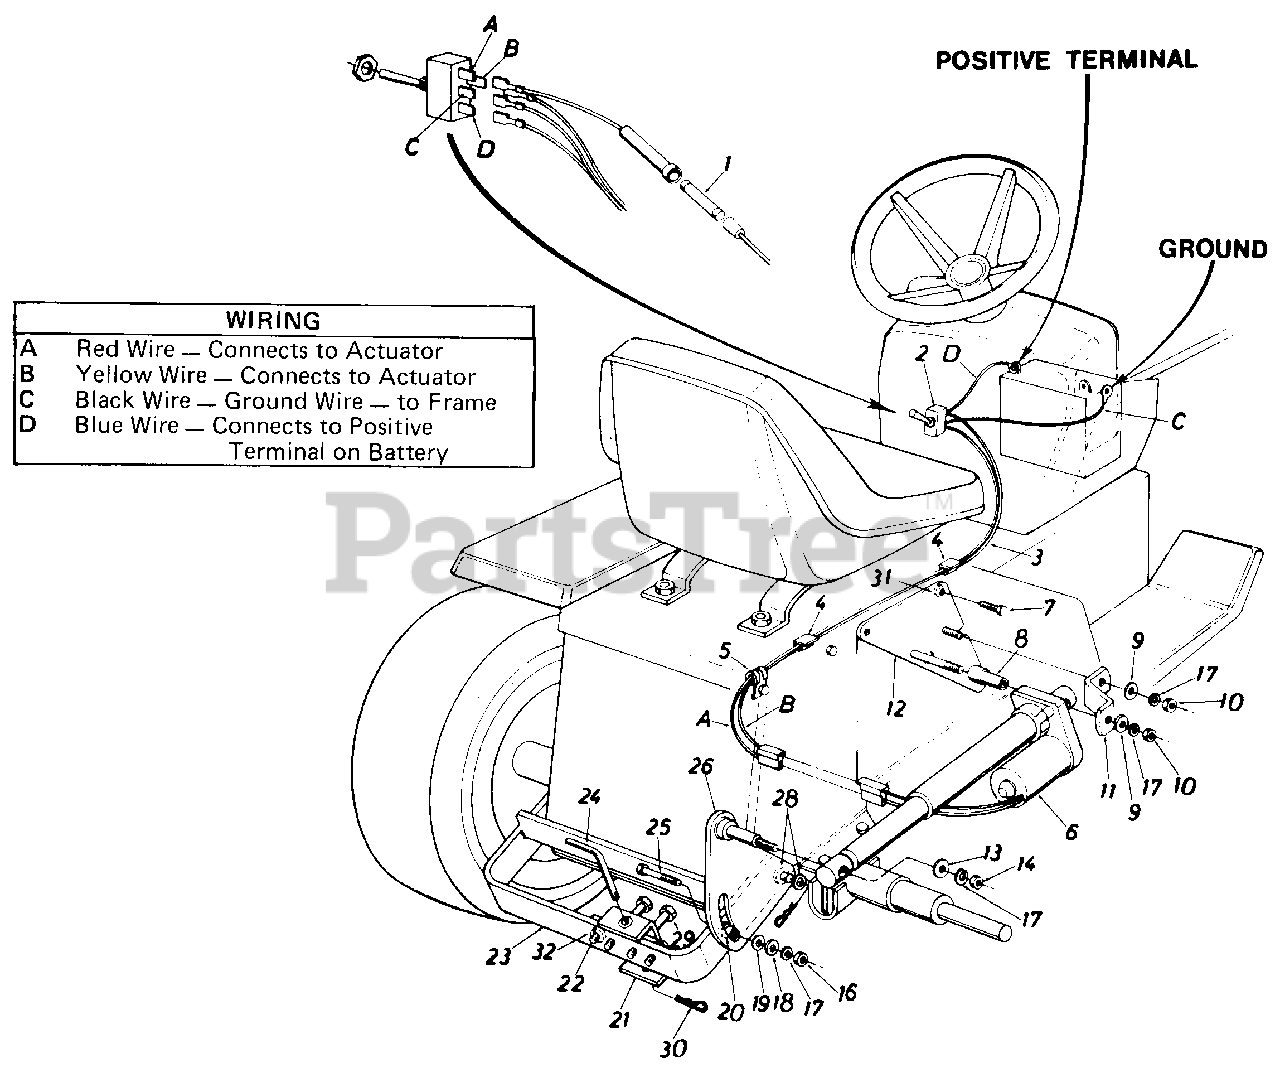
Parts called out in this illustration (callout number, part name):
1	Fuse 30 AMP
2	Toggle Switch
3	Wire Harness
4	Adjustment Clamp
5	Clamp
6	Electric Actuator
7	Hex Wash. TT. Tap Scr. 5/16 x .62" Lg.
8	Spacer Special for Actuator
9	Fl.-Wash. .378" I.D. x 1.00" O.D. x .125 Thk.
10	Hex Nut 3/8-16 Thd.*
11	Bracket Actuator Mounting
12	Mounting Plate Ass'y.
13	Fl.-Wash. .385" I.D. x .87" O.D. x .060 (H.T.)
14	Hex Nut 3/8-16 Thd.*
16	Hex Nut 3/8-16 Thd.*
17	L. Wash. 3/8" I.D.
18	Fl.-Wash. .378" I.D. x 1.00" O.D. x .125" Thk.
19	Fl.-Wash. .635 I.D. x 1.00" O.D. x .030" Thk. (H.T.)
20	Shoulder Spacer
23	Hitch Bar Ass'y.
24	Hitch Pin
25	Hex Bolt 3/8-16 x 1.75" Lg.*
26	Lifting Plate Ass'y.
28	Fl.-Wash. .63" I.D. x 1.12" O.D. x .100 Thk.
29	Hex Bolt 1/2-13 x 3.00" Lg.*
30	Intern. Cotter Pin 5/8" Dia.
31	Fl.-Wash. .378" I.D. x 1.00" O.D. x .125
32	L-Wash. 1/2" I.D.*
